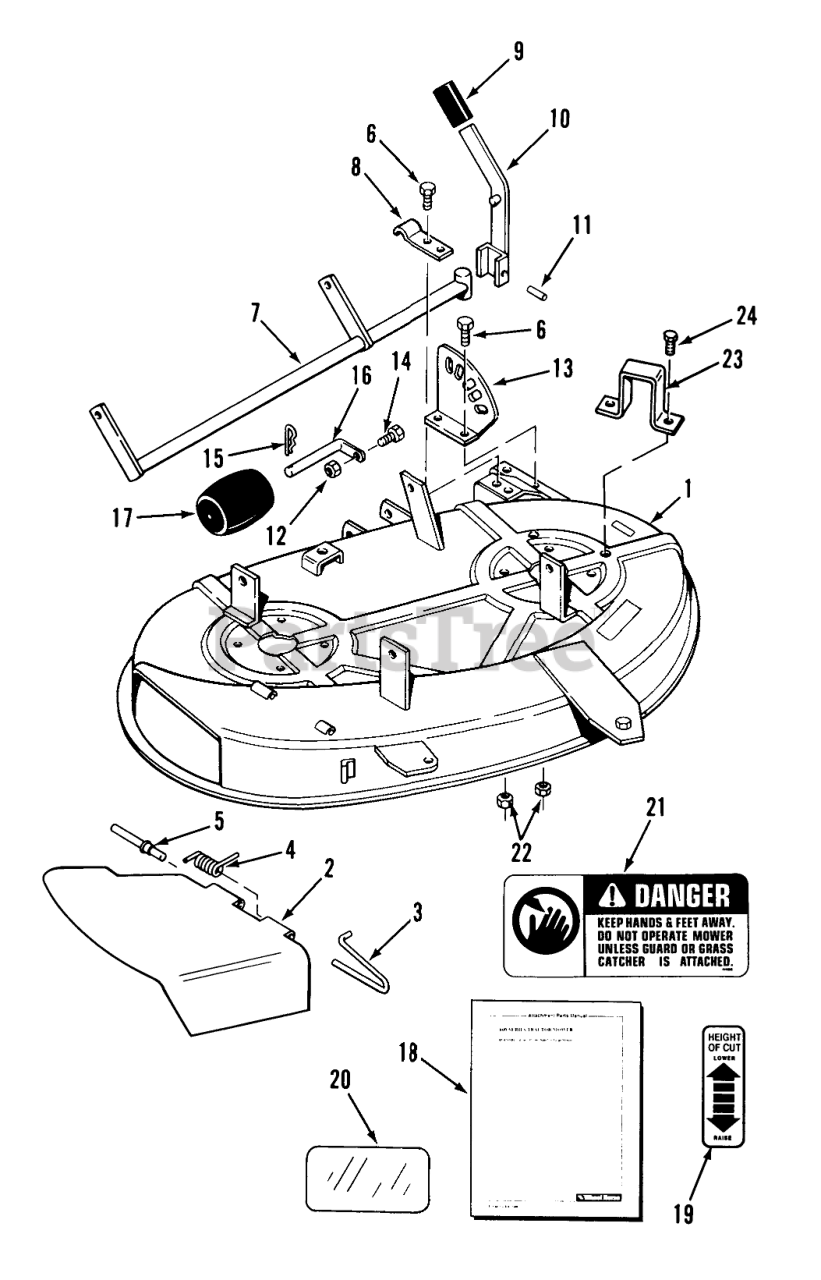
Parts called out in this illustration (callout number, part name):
1	Deck-Mower
2	Chute-Discharge
3	ROD-HINGE FRONT
4	SPRING-TORSION
5	ROD-HINGE REAR
6	Bolt
7	Shaft-Lift
8	Bracket-Pivot
10	WLDMT-MWR LIFT LE R
11	SPIROL PIN 3/8X1 1/2
12	Nut
13	Quadrant
14	Bolt
15	Cotter Pin
16	SHAFT-ROLLER
17	ROLLER
18	Operator-s Manual
19	DECAL-HOC
20	DECAL-OVERLAY
21	Danger Decal
22	NUT
23	STOP-DECK R
24	Screw
